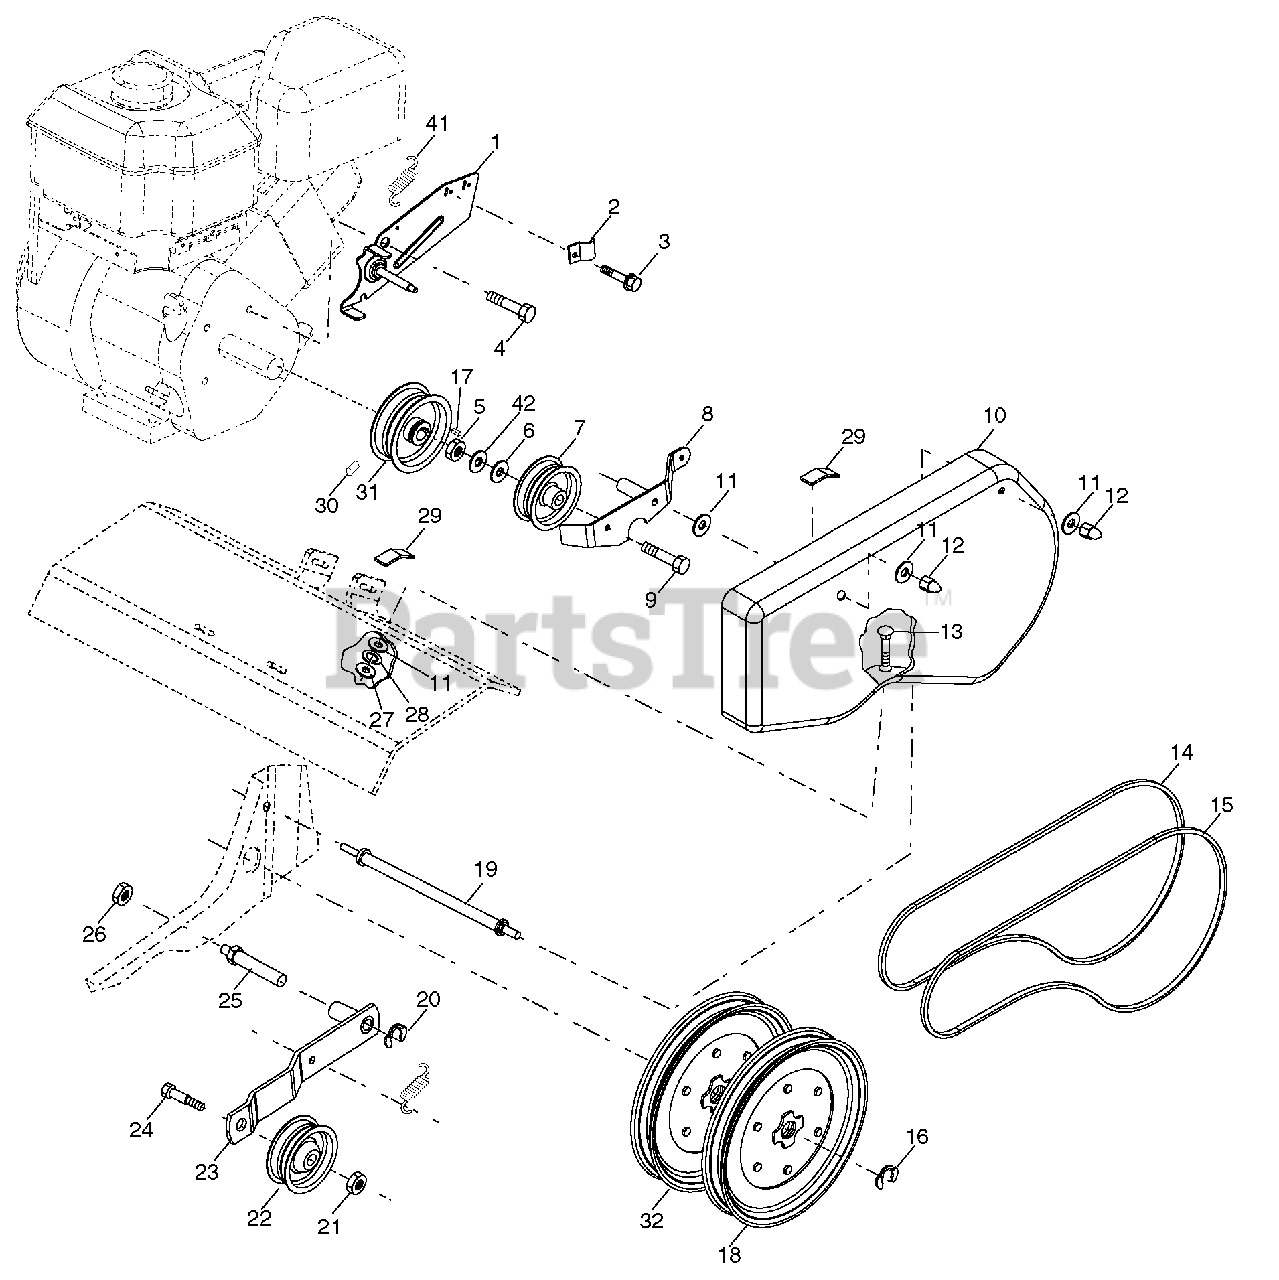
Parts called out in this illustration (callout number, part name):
1	Bracket Assembly, Belt Guard
2	Clip, Cable
3	Screw, Hex Washer Head, Slotted, Thread Cutting #10-24 x 1/2
4	Bolt, Hex Head 1/2-20 x 3/4
5	Locknut, Hex 3/8-16
6	Washer, 13/32 x 13/16 x 16 Ga.
7	Pulley, Idler, Reverse
8	Reverse Idler Arm Assembly
9	Bolt, Hex Head 3/8-16 x 1-3/4
10	Guard, Belt
11	Washer 9/32 x 5/8 x 16 Ga.
12	Nut, Hex, Cap 1/4-20
13	Bolt, Carriage 1/4-20 x 3/4
14	V-Belt (Forward Motion)
15	V-Belt (Reverse)
16	Ring, Retainer
17	Key, Square
18	Pulley, Flat, Transmission
19	Bolt, Belt Guard
20	Ring, Klip
21	Nut, Hex, Jam 3/8-16
22	Pulley, Idler
24	Bolt, Hex Head 3/8-16 x 1-1/4
25	Shaft, Idler Arm
26	Nut, Hex, Jam 5/16-18
27	Nut, Hex 1/4-20
28	Washer, Lock, HH Spring 1/4
29	Pad, Idler
30	Set Screw, Headless, C.P.1/4-20 x 1/4
31	Sheave, Engine
32	Pulley, V-Groove, Transmission
41	Spring
42	Spacer
